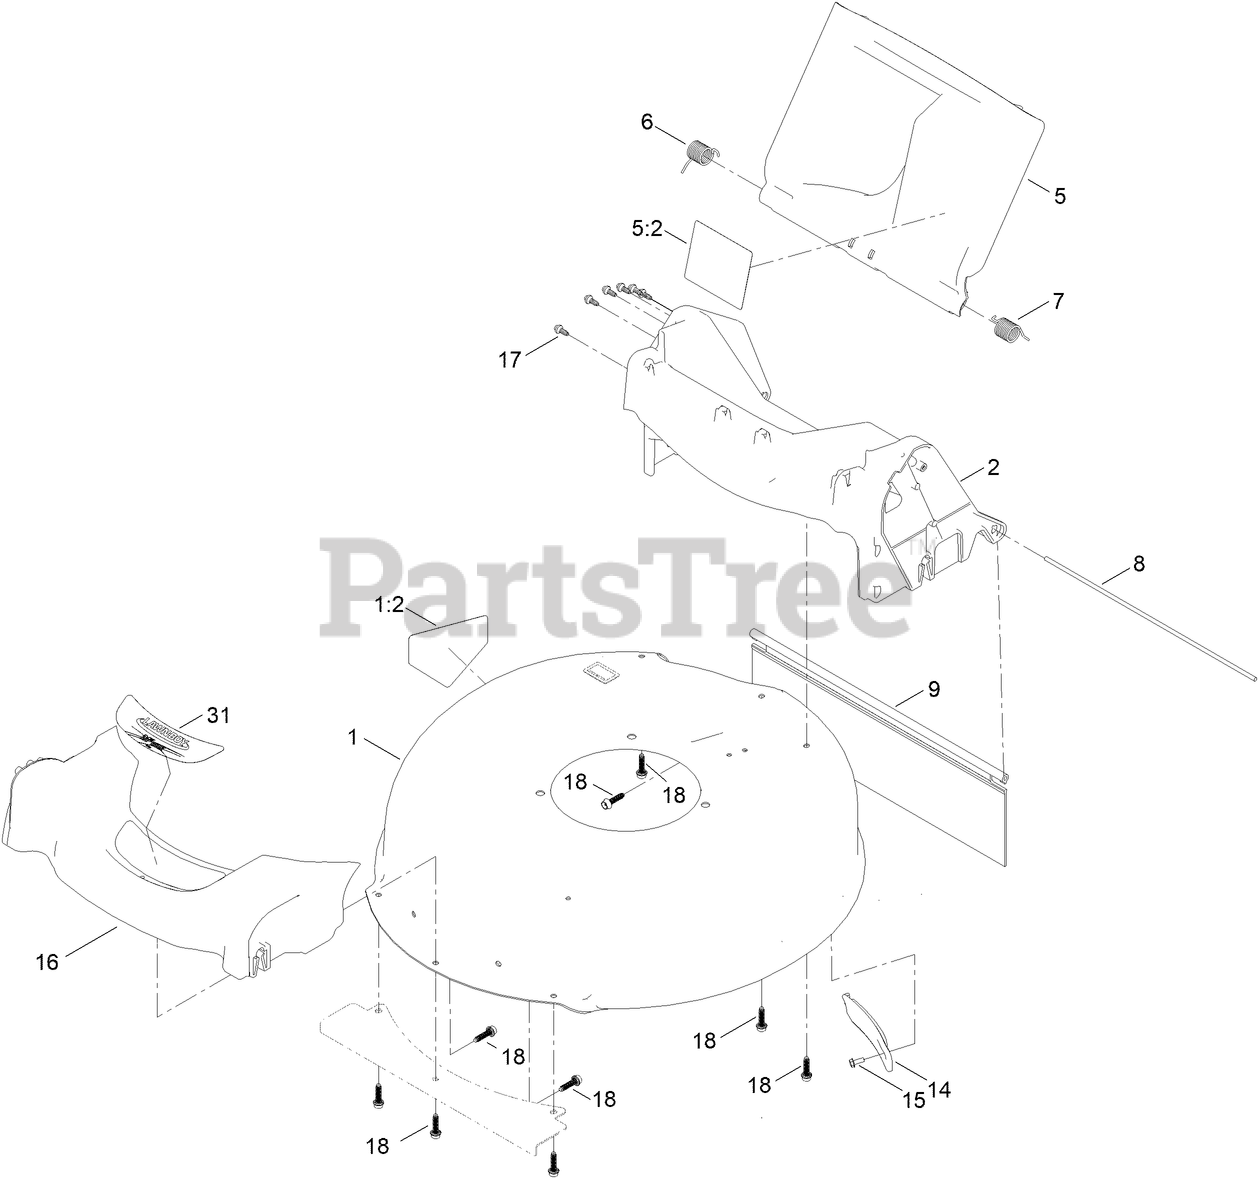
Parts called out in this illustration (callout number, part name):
1	HOUSING ASM
1:2	DECAL-DANGER
2	CHUTE ASM
5	REAR DEFLECTOR ASM
5:2	DECAL-WARNING
6	SPRING-TORSION
7	SPRING-TORSION
9	SHIELD-TRAILING
14	COVER-BELT
15	SCREW-TAPTITE
18	SCREW-FLANGE, PLASTIC
31	DECAL-DECK
